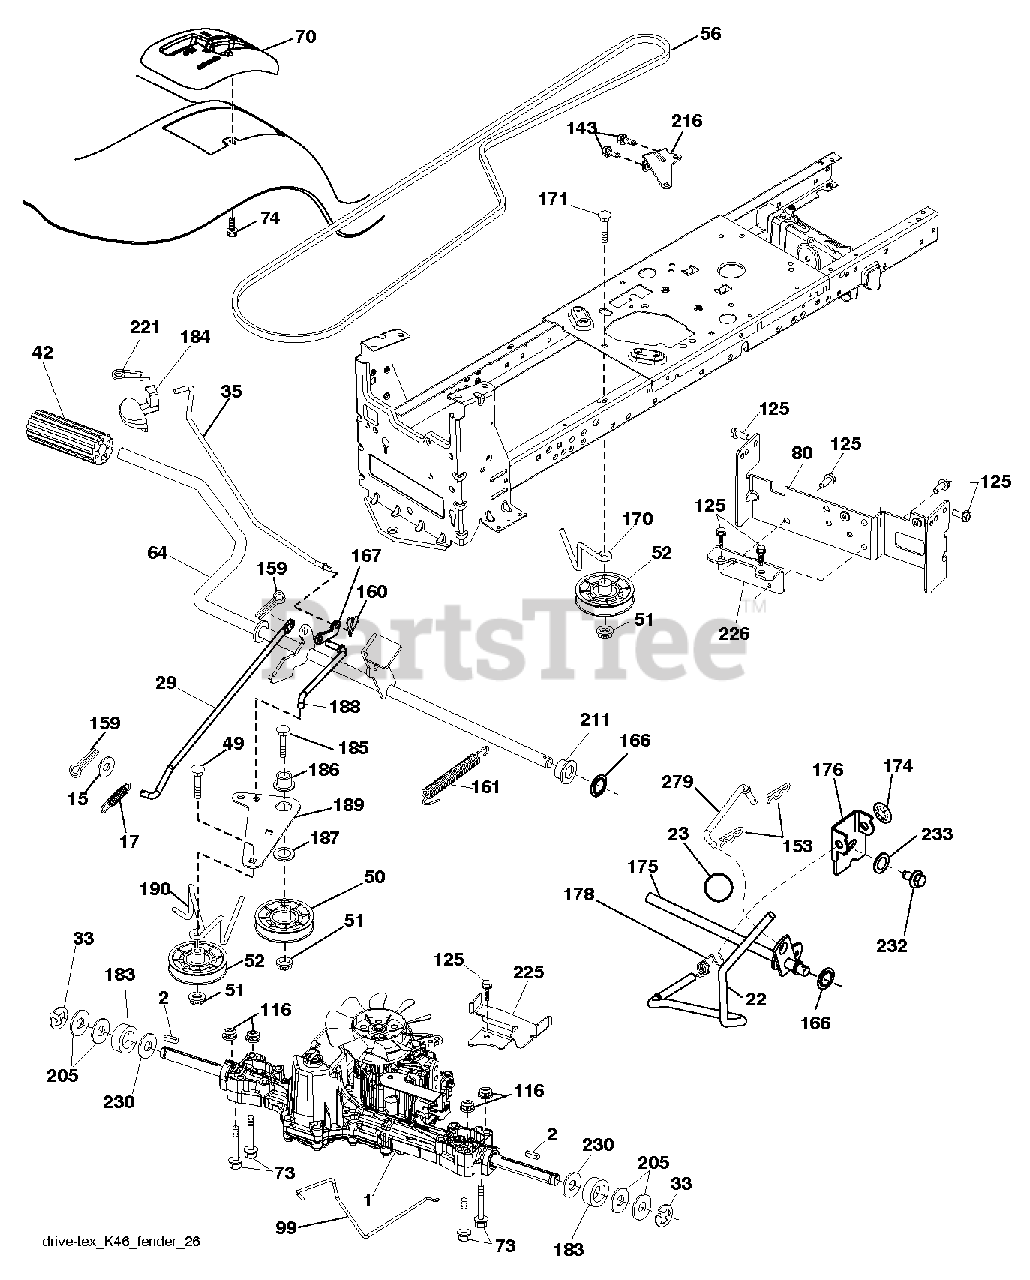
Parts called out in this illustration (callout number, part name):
1	Poulan TBD
2	SQUARE KEY
17	SPRING.BRAKE.K46.GREEN
22	ROD.SHIFT.FENDER.TLT.2006
23	KNOB.DELUXE.(PISTOL.GRIP).BLAC
29	ROD.BRAKE.K46
33	E-RING LT
35	ROD.BRAKE.PARKING.LT.T
49	BOLT
50	IDLER.FLAT.910.OFFSET
51	NUT LOCK FLG 3/8-16 UNC
52	IDLER.V-GROOVE.910.OFFSET
56	V-BELT.MOWER.92.40.42/K46
64	SHAFT.ASM.PEDAL.BRAKE.
70	CONSOLE.SHIFT.STL.HYD.BLACK
73	BOLT HEX 5/16-18 GR 5
74	SCREW.HI-LO.CONSOLE
80	STRAP.TORQUE.K46.K57R.TT
99	ROD.SPRING.BYPASS.K46.LT.Z
116	NUT LOCK HEX FLANGE 5/16-18
125	SCREW
143	SCREW LT
159	COTTER PIN
160	RETAINER CLIP
161	SPRING, RETURN LT
166	NUT.PUSH.625
167	LATCH.BRAKE.SPRING
170	KEEPER.V-IDLER.CENTER.
171	BOLT
174	NUT.PUSH.500.2006
175	SHAFT ASM SHIFT
176	ARM.CLEVIS.ROD.SHIFT
178	SPRING.SHIFT.GT2006
183	SPACER AXLE
184	HANDLE.PARKING.BRAKE.LTTEX.667
186	SPACER.RETAINER
187	WASHER 12/32X2X10GA
188	LINK.CLUTCH.GROUND.DRIVE
189	BELLCRANK.GROUND.DRIVE.TEX.
190	KEEPER.BELLCRANK.DRIVE
211	BUSHING.SHAFT.BRAKE.HAND
216	BRACKET.PULLEY.IDLER.W/TEX
221	RETAINER.SPRING.CLIP.H
225	KEEPER.BELT.TRANSAXLE.K46
226	BRACKET.MOUNT.TORQUE.K46.TLT
230	WASHER.HARDENED
232	BOLT FIN HEX 7/16-14 X 1
233	WASHER SERRATED
279	LINK.SHIFT.T/A.K46.FEND.TX
